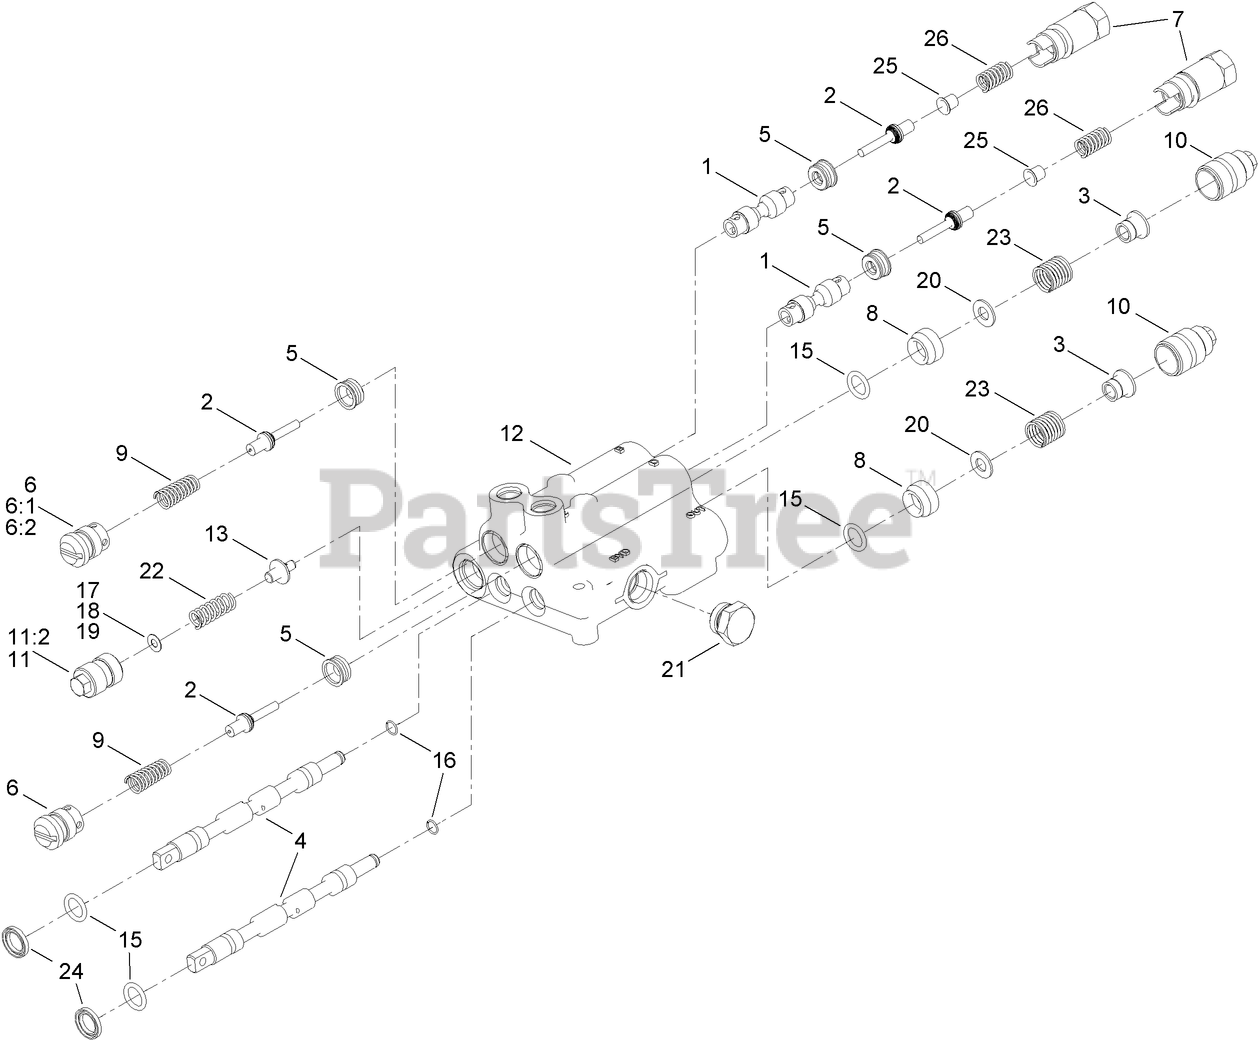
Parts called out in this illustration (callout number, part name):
1	PLUNGER
2	POPPET
3	SPACER
5	SEAT-HARDENED
6	PLUG ASM
6:1	O-RING
6:2	Washer-Backup
8	BUSHING
9	LOCK-SPRING
11	PLUG ASM
11:2	O-RING
12	Body
13	POPPET
15	O-RING
16	RING-RETAINING
17	WASHER
18	WASHER
19	WASHER
20	WASHER
21	PLUG ASM
22	Spring
23	SPRING
24	WIPER
25	EYELET
26	SPRING
